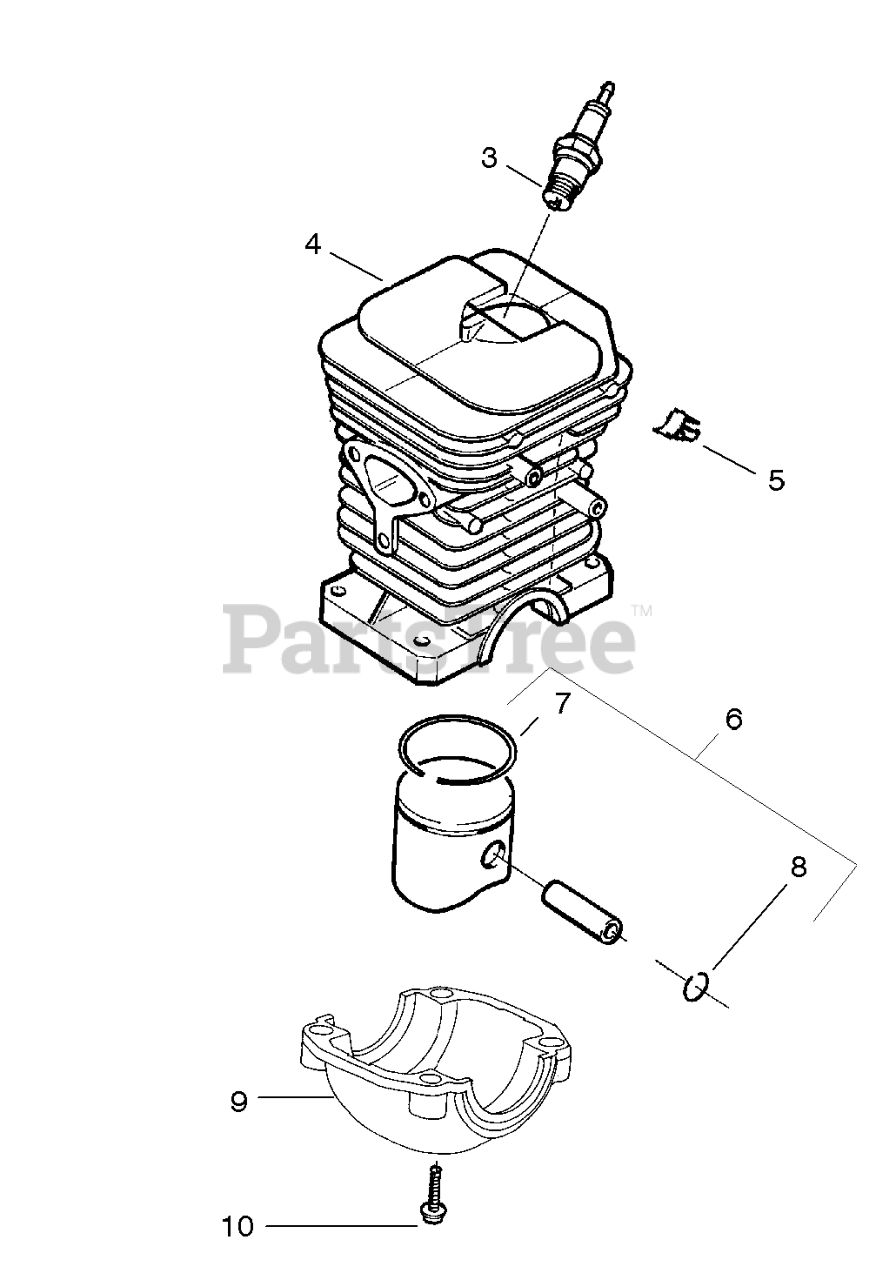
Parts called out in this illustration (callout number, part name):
3	Spark Plug
4	CYLINDER ASSY/141
5	CLIP - HIGH TENSION LE
6	KIT-PISTON
7	PISTON RING HV41
8	C-CLIP,PSTN PIN 36/41
9	CAP-CRANKSHAFT
10	SCREW-M5-0.8 X 25MM(TAP)
